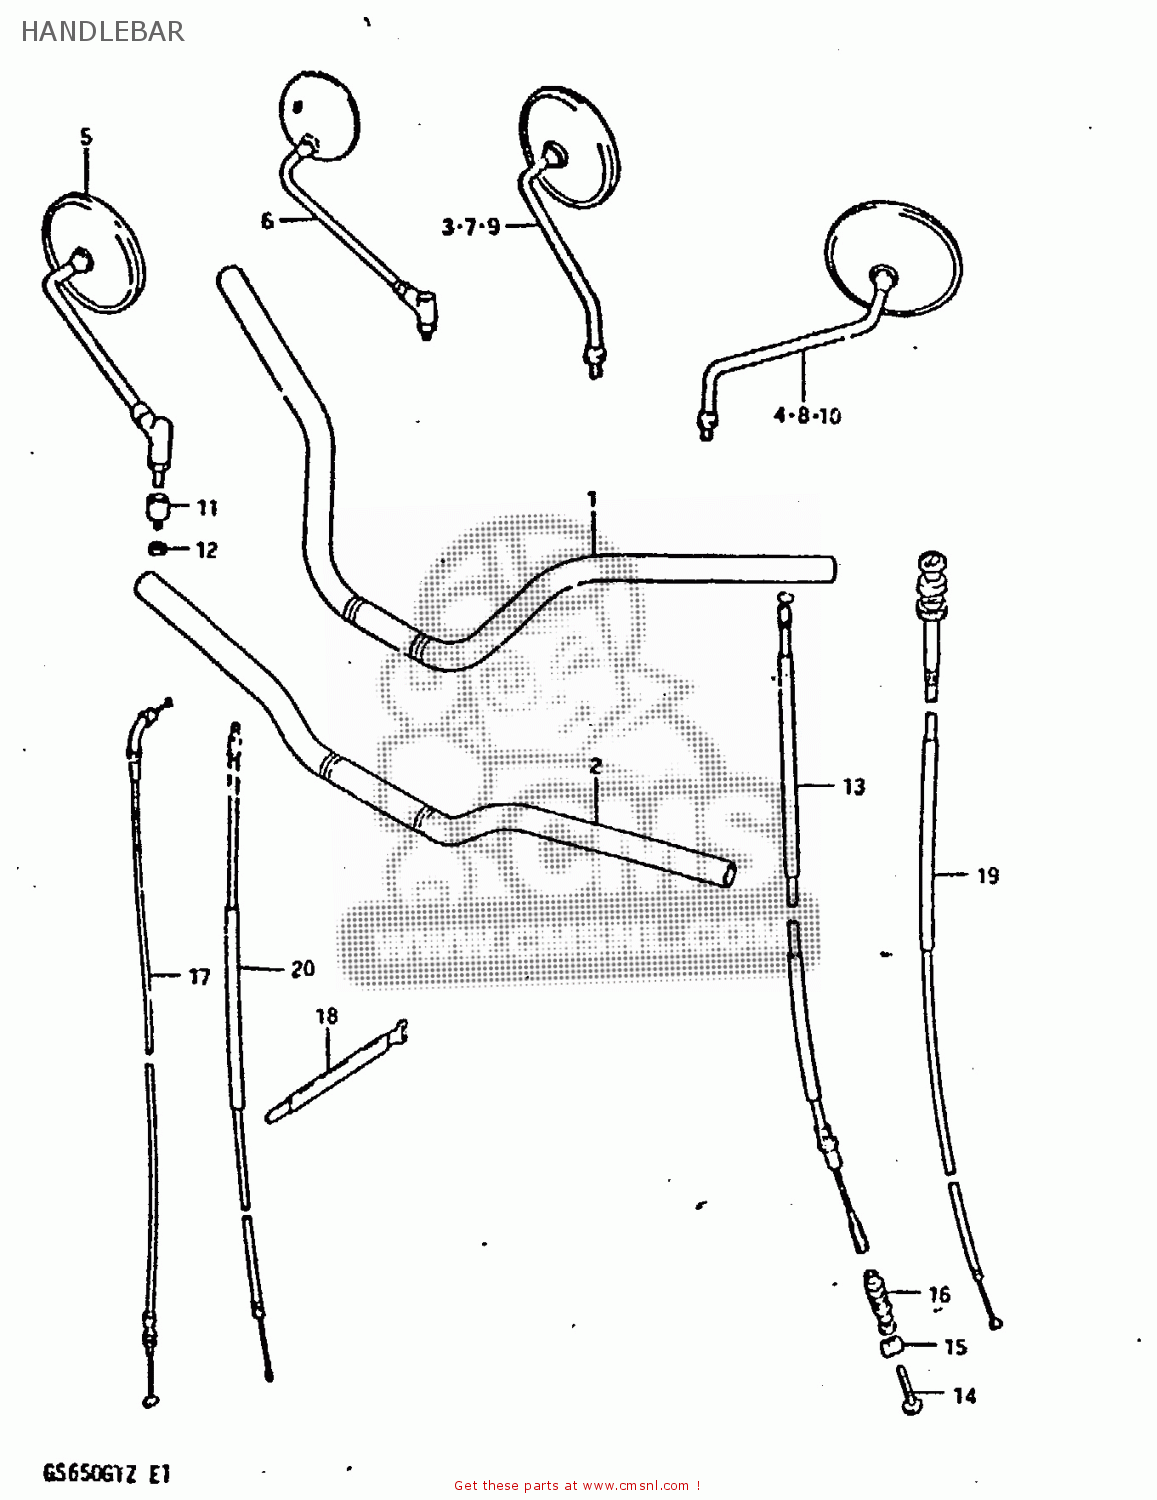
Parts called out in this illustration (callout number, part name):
1	HANDLEBAR (NERTRAL)
2	HANDLEBAR (FLAT)
5	MIRROR ASSY,RH
11	CUSHION,REAR VIEW MIRROR
12	NUT
13	CABLE, CLUTCH (FLAT)
14	SCREW
15	PIN
16	DUST SEAL
17	CABLE ASSEMBLY,THROTTLE
18	CLAMP
19	CABLE ASSEMBLY,STARTER
20	CABLE, STARTER (FLAT)
